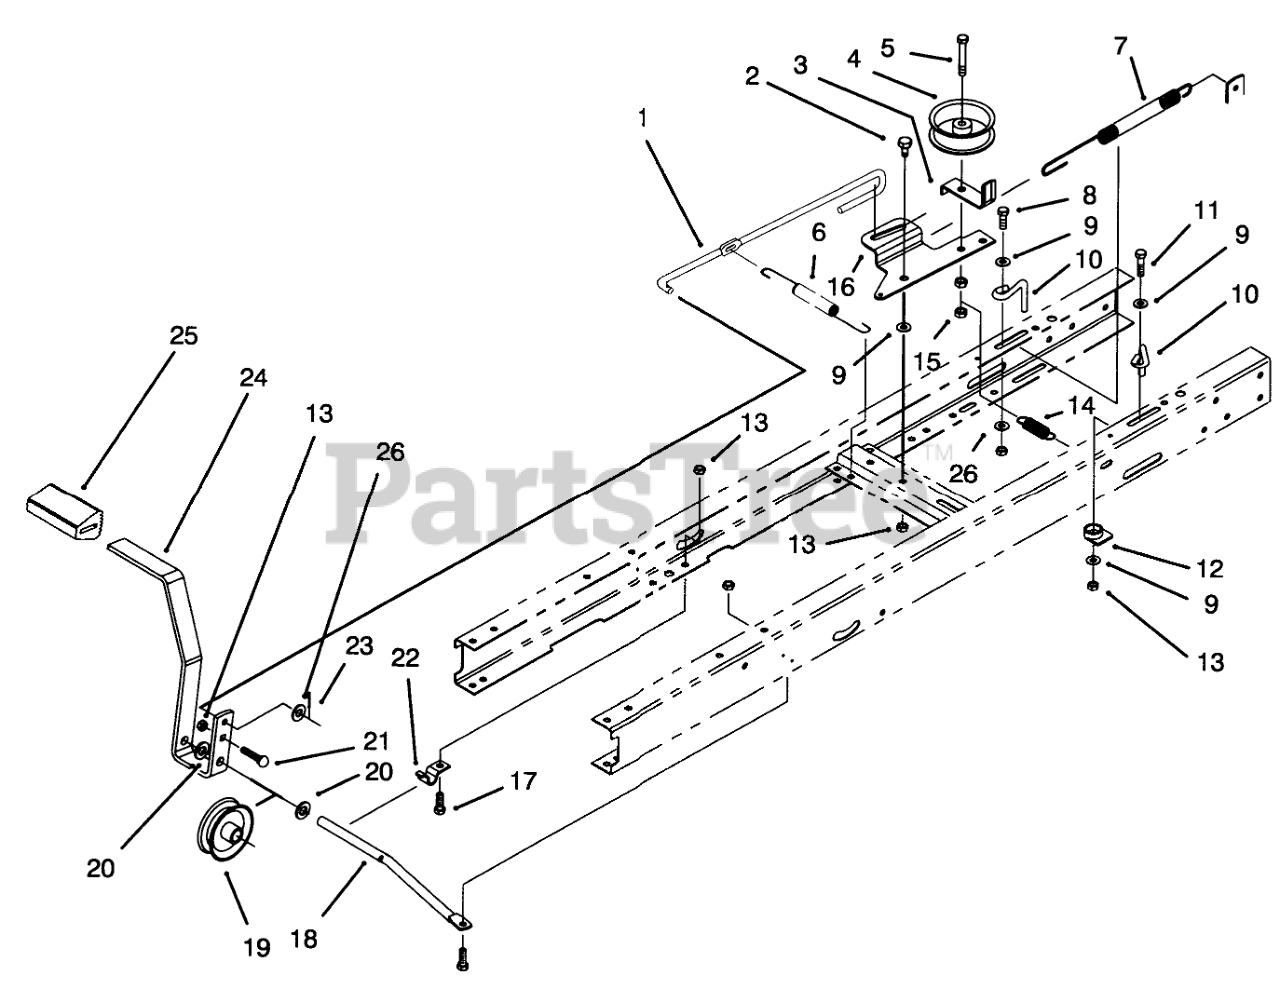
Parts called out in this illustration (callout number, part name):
1	ROD-CLUTCH/BRAKE
2	BOLT-SHOULDER
3	GUIDE-IDLER, BELT
4	Idler Pulley
5	SCREW-HH
6	SPRING-EXTENSION
7	BRAKE SPRING
8	SCREW-HH
9	WASHER-PIVOT
10	TRANS BELT GUIDE
11	SCREW-HH
12	GUIDE-CABLE
13	NUT-LOCK, NI
14	SPRING-EXTENSION
15	NUT-LOCK, NI
16	ARM-IDLER
17	SCREW-HH
18	ROD-PIVOT, PEDAL
19	PULLEY, CABLE
20	WASHER-FLAT
21	SCREW-CARR
22	CLAMP-PIVOT, SHIFT
23	PIN-COTTER
24	Pedal-Clutch/Brake
25	PAD-PEDAL
26	WASHER-PLAIN
